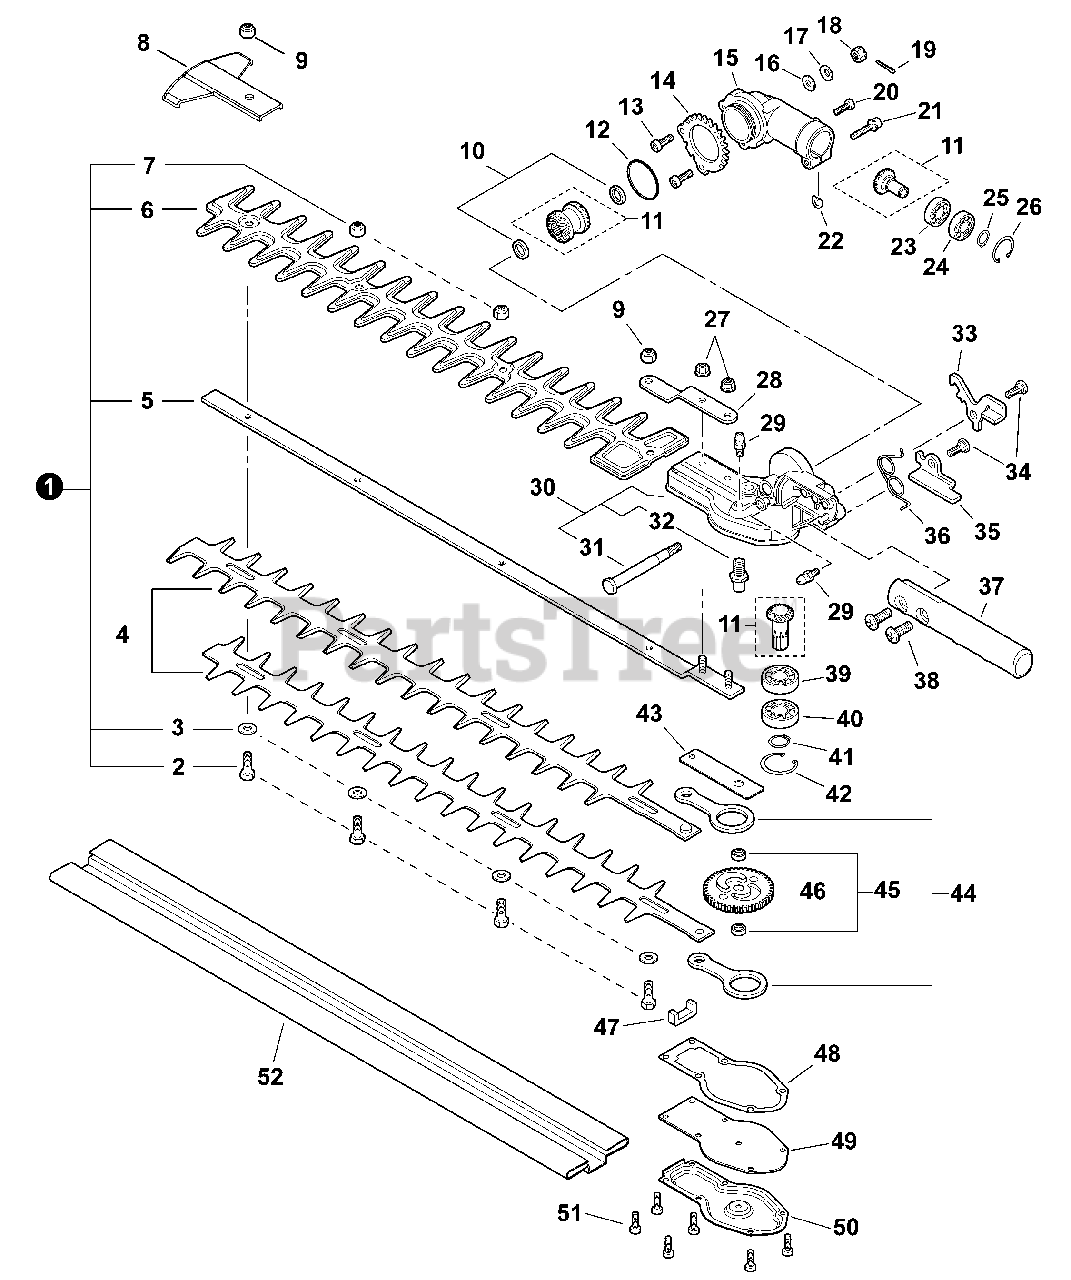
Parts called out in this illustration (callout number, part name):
1	CUTTER ASSY, 22"
2	BOLT M6×20
3	WASHER M6
4	CUTTER 22"
5	GUIDE BAR 22"
6	GUARD, CUTTER BLADE
8	GUARD, TIP
10	COLLAR Ø16ר10×L= 2
11	GEAR SET
13	BOLT 5×12
14	RING, LOCKING
15	HOUSING, UPPER GEAR CASE
16	WASHER 6.5×13×1
17	WASHER, CONE M6
19	PIN, COTTER Ø1.6×15
20	BOLT 5×12
21	BOLT M5×25
22	D-WASHER
23	BEARING, BALL 609
24	BEARING, BALL 609ZZ
25	RING, SNAP Ø9
26	RING, SNAP Ø24
28	BRACKET, CUTTER
29	FITTING, GREASE
30	GEAR CASE HOUSING ASSY
32	MAINSHAFT
33	LEVER, LOCK
34	BOLT M6
35	RELEASE, LOCK
36	SPRING, TORSION
37	LEVER, ADJUSTMENT
38	SCREW, TRUSS M6×20
39	BEARING, BALL 6001
40	BEARING, BALL 6001ZZ
41	RING, SNAP Ø12
42	RING, SNAP Ø28
43	PLATE, GUIDE
45	SPACER Ø11ר8×3.4
46	GEAR, CAM
47	PACKING, FELT
48	GASKET, GEAR CASE
50	COVER, GEAR CASE
51	BOLT 4×10
52	SCABBARD
